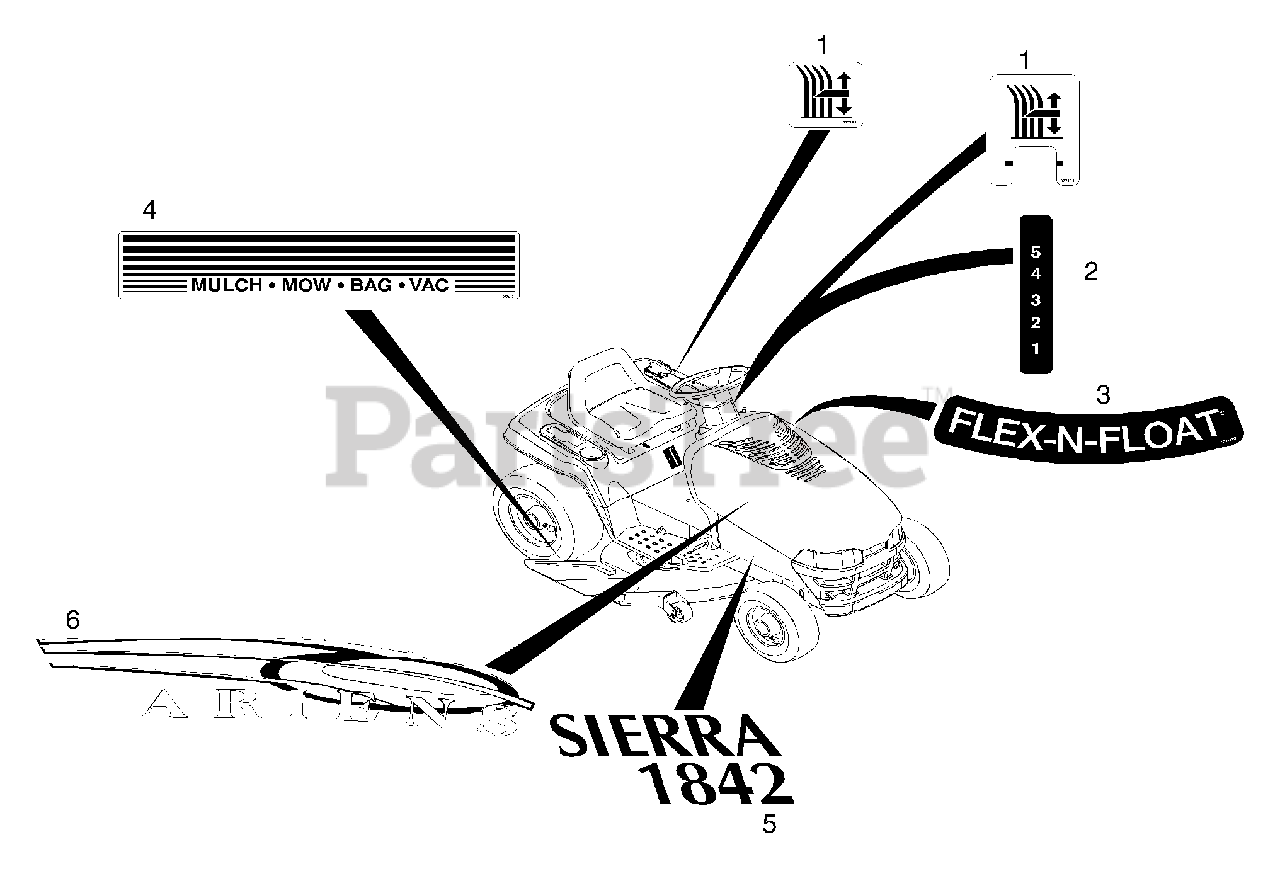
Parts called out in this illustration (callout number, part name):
1	DECAL SET - SIERRA
2	DECAL, INDICATOR
3	DECAL FLEX-N-FLOAT
4	DECAL- MULCH-MOW-BAG-VAC
5	DECAL-SIERRA 1842 RIGHT
6	DECAL SET SIERRA HOOD
